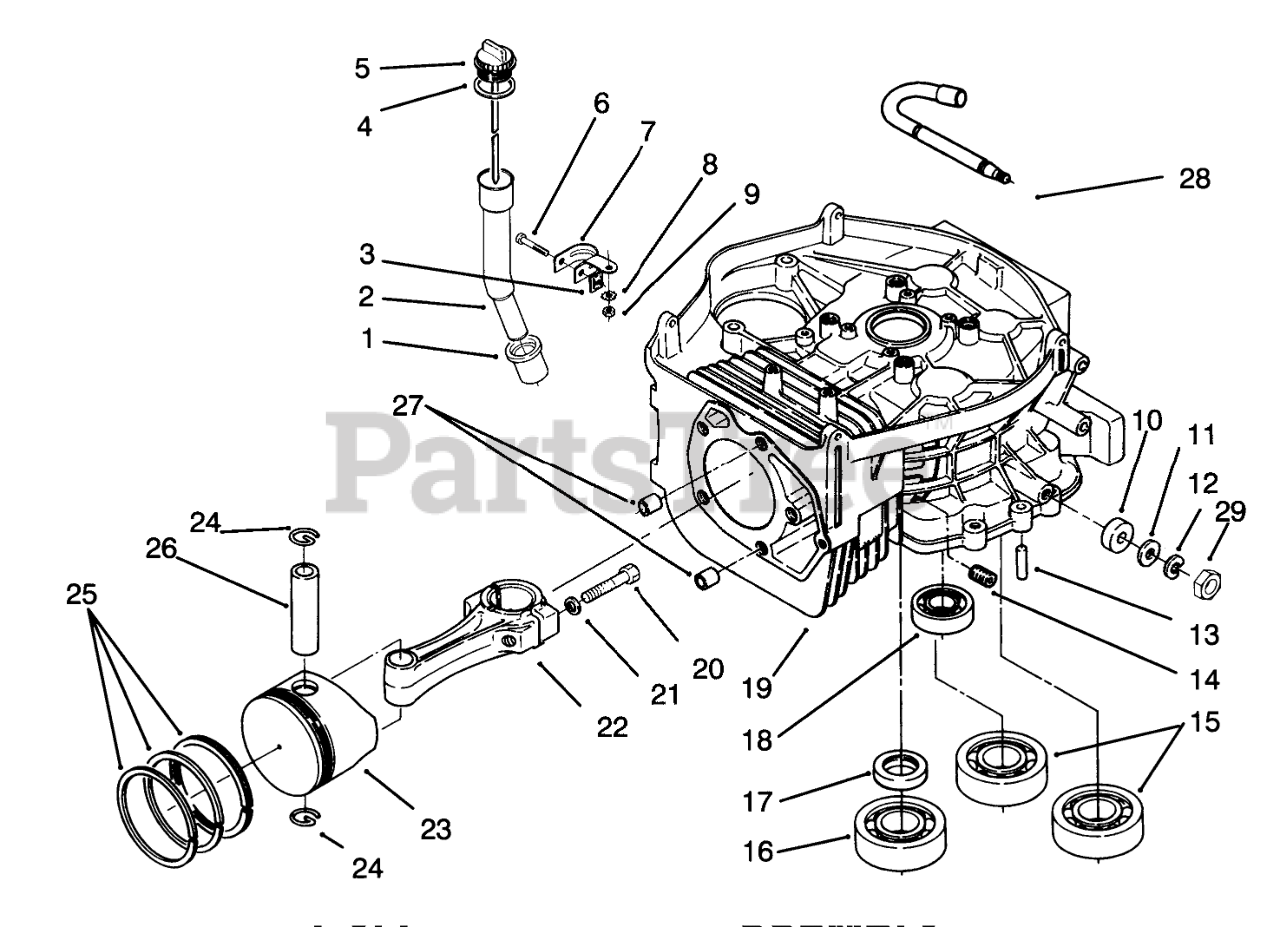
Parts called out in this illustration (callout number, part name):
1	Seal
3	NUT - SPEED
4	SEAL 0-RING
5	INDICATOR
6	SCREW - PAN HEAD
7	BRACKET
8	WASHER
9	HEX NUT
10	SEAL-GVR SHAFT LEVER
11	WASHER-FLAT
12	CLIP-RETAINER
13	PIN-ALIGNMENT
14	PLUG-COUNTERSUNK HD
15	BRNG-BALL BAL SHFT L
16	BEARING-BALL CRANKSH
17	SEAL-OIL CRNKSHFT UP
18	BEARING-BALL CAMSHFT
19	SHORT BLOCK
20	Bolt
21	WASHER-CONN ROD
22	Kit-Connecting Rod STD (Incl. Ref. #12-13)
23	Kit-Piston (Standard) (Incl. Ref. #8-9)
24	RING-RETAINING
25	PISTON RING SET
26	PIN-PISTON
27	PIN-DOWEL HOLLOW
28	GOV LEVER SHAFT
29	NYLON LOCK NUT
